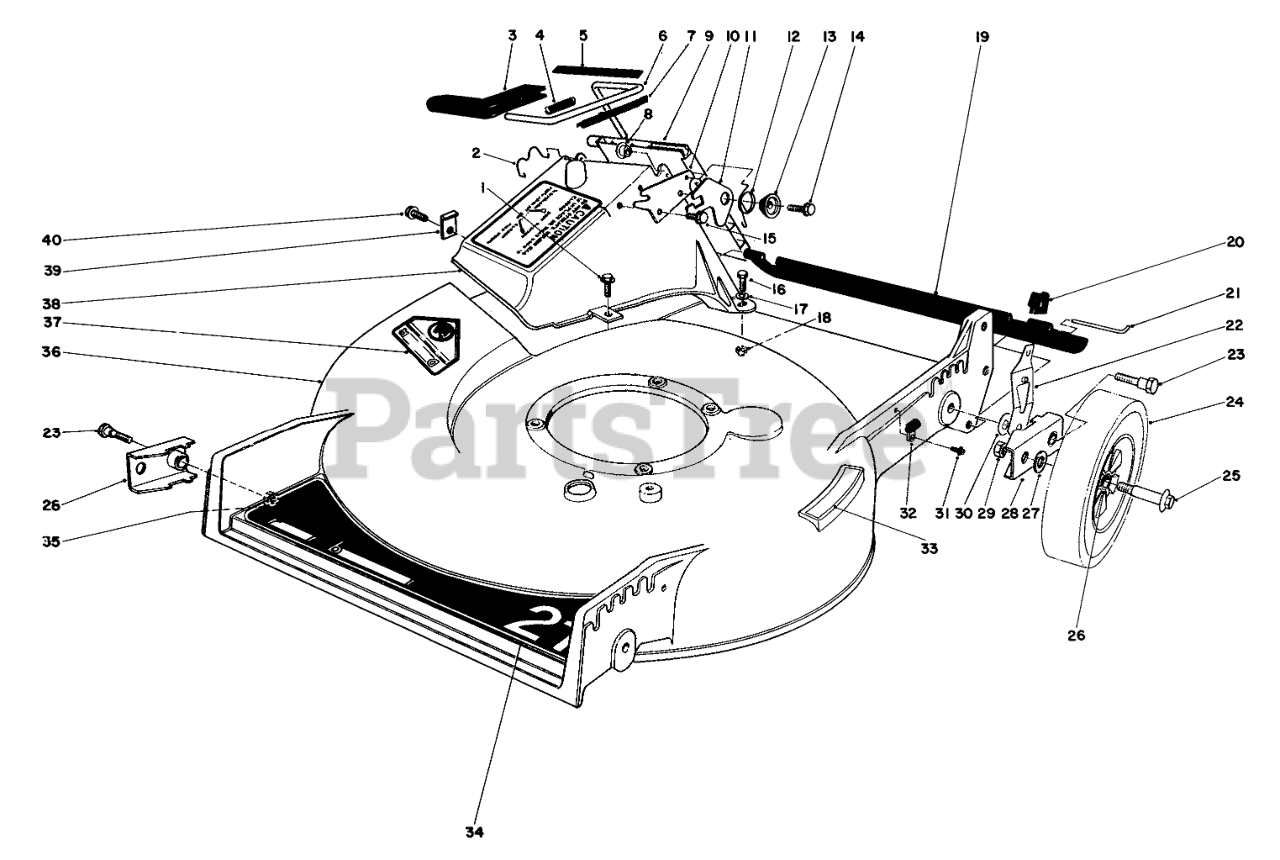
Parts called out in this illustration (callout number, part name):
1	Screw
2	DOOR RET SPRING
3	Handle-Door
4	Spring
5	DOOR COVER
6	DOOR ROD +
7	DOOR HANDLE COVER
8	BUSHING-NYLON
9	Door Discharge
10	DOOR LATCH PLATE
11	SAFETY LATCH
12	TORSION SPRING
13	DOOR SPACER
14	SCREW-HWH
15	SCREW-PLASTITE
16	SCREW-HH
17	WASHER-FLAT
18	NUT-LOCK, NI
19	SHIELD - TRAILING
20	KNOB-ARM
21	Rod Shield
22	Spring Arm
23	PIVOT SCREW
24	Wheel & Tire Assembly (Incl. Ref. #26)
25	BOLT-WHEEL
26	BUSHING
27	WASHER
28	HP PIVOT ARM ASM
29	Nut
30	WASHER-PIVOT
31	SCREW
32	CLAMP-CABLE
33	STEP PAD DECAL
34	DECK DECAL
35	NUT-LOCK, NI
36	Housing (Incl. Ref. #33 & 37)
37	DECAL-DANGER
38	Tunnel Discharge
39	TUNNEL CLIP
40	SCREW
